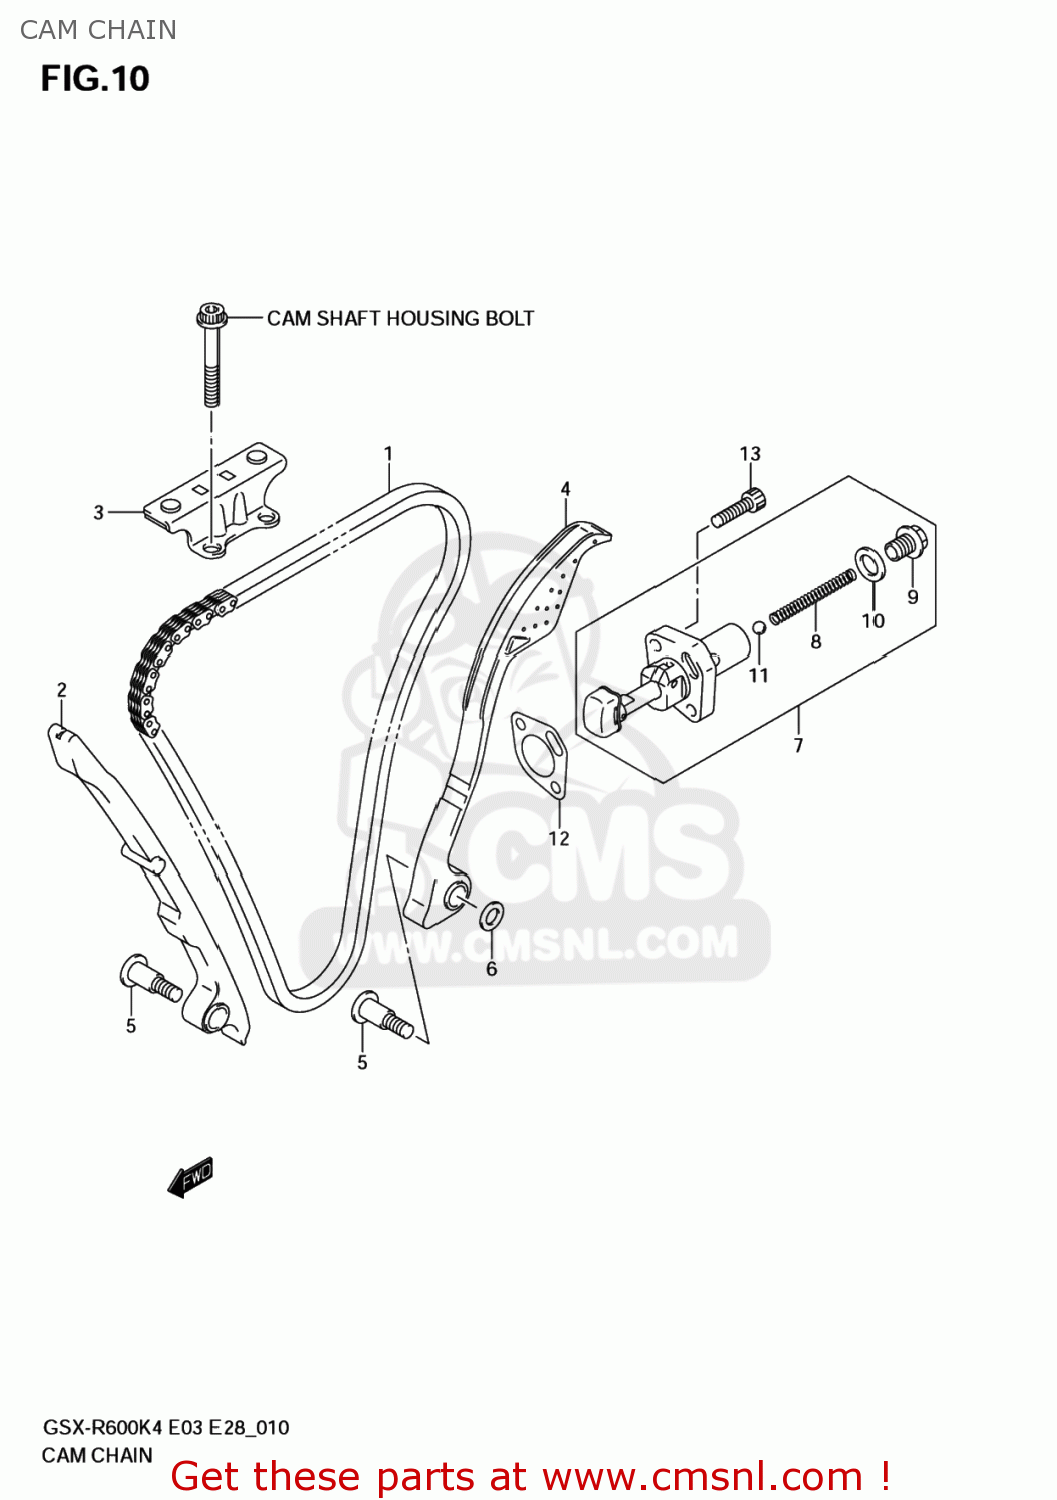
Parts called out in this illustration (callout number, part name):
1	CHAIN,CAMSHAFT DRIVE
2	GUIDE,CAM CHAIN NO.1
3	GUIDE,CAM CHAIN NO.2
4	TENSIONER,CAM CHAIN
5	BOLT,CAM CHAIN TENSIONER/GUIDE
6	WASHER,CAM CHAIN TNSN
7	ADJUSTER ASSY,
8	SPRING
9	PLUG,FR TENSIONER ADJ
10	GASKET,TENSIONER ADJUSTER (NAS)
11	BALL
12	GASKET,TENSIONER ADJUSTER (NAS)
13	BOLT,CL.COVER
